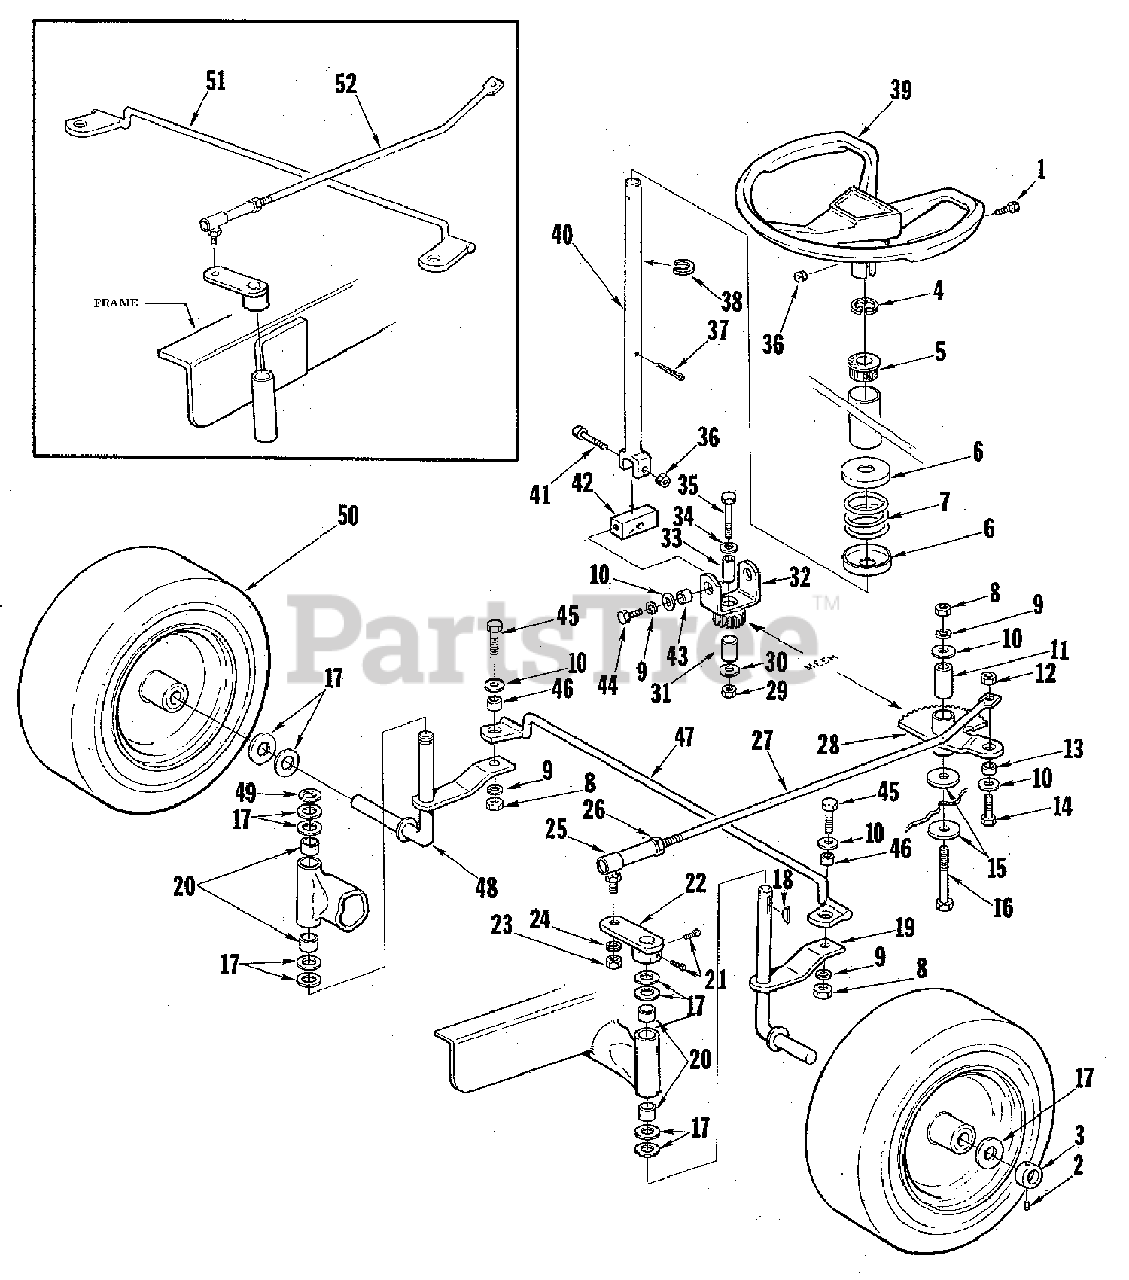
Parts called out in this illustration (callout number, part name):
1	CAPSCREW, Hex Head, 5/16-18 x 1-1/4
2	SETSCREW, Socket Cap, 5/16-18 x 5/16
4	RING, Retaining
5	BUSHING, Steering
7	SPRING, Compression
9	LOCKWASHER, 3/8
12	NUT, Hex Lock, 3/8-16
14	CAPSCREW, Hex Head, 3/8-16 x 1
15	WASHER, Special
16	CAPSCREW, Hex Head, 3/8-16 x 2-1/2
19	SPINDLE ASSEMBLY, L.H.
20	BUSHING, Press
21	SETSCREW, 5/16-18 x 1/2
22	LEVER ASSEMBLY, Steering, L.H.
23	NUT, Hex, 1/2-20
24	LOCKWASHER, Regular, 1/2
26	NUT, Jam, Hex, 1/2-20
28	GEAR ASSEMBLY, Steering
29	NUT, Lock, Hex, 3/8-16
32	FORK & PINION ASSEMBLY
34	WASHER, 5/16
35	CAPSCREW, Hex Head, 3/8-16 x 1-1/2
36	NUT, Lock Hex, 5/16-18
39	WHEEL ASSEMBLY, Steering
40	SHAFT ASSEMBLY, Steering
41	CAPSCREW, Special
42	PIN, Universal Joint
44	CAPSCREW, 3/8-16 x 3/4
45	SCREW, Special
47	LINK ASSEMBLY, Drag
48	SPINDLE ASSEMBLY, R.H.
49	RING, Retaining
50	WHEEL & TIRE, Front
51	ROD ASSEMBLY, Tie
